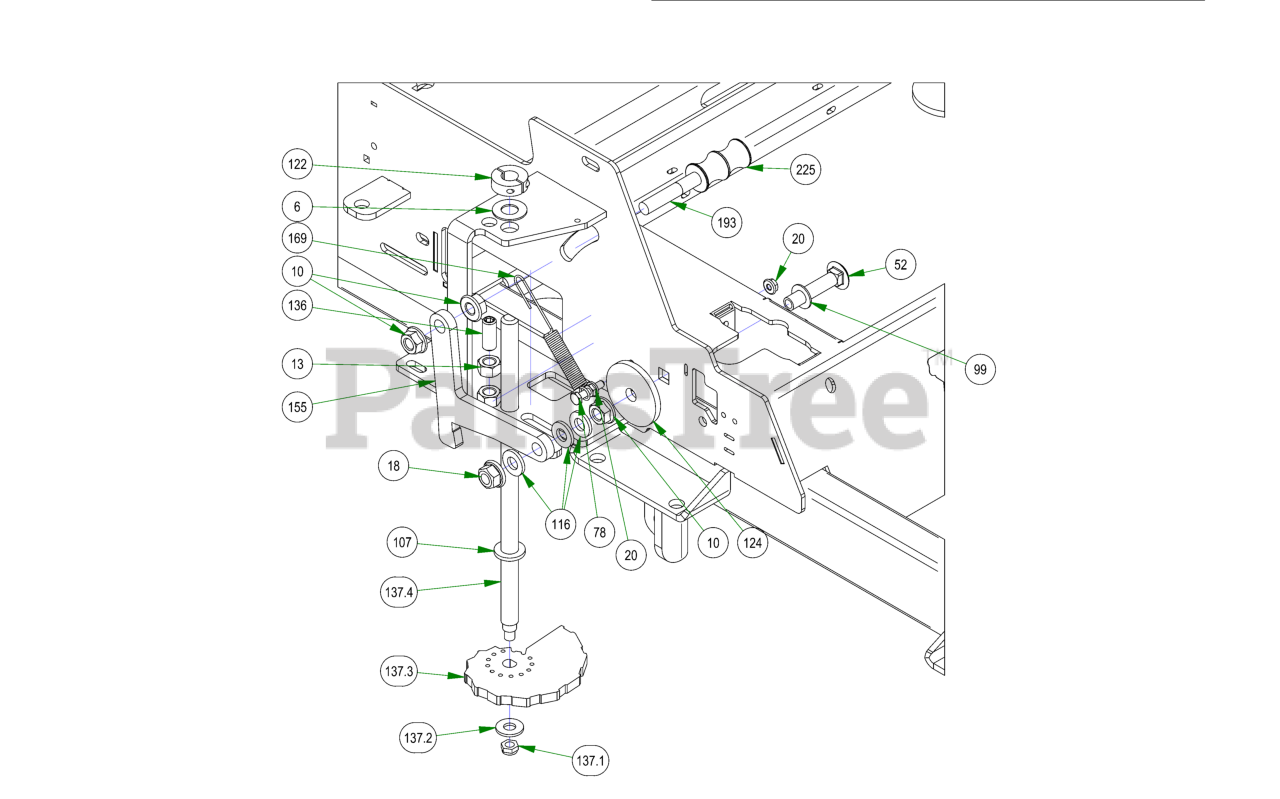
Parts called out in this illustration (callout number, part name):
6	.625 ID x 1.250 OD x .062 THK F/W Nylon
9	3/8-16 NYLON INSERT FLANGE LOCKNUT (GR.F) ZINC
10	1/2-13 HEX SERRATED FLANGE NUT HARD/ZINC
13	1/2-13 HEX NUT ZINC
18	1/2-13 NYLON INSERT FLANGE LOCKNUT ZINC
20	1/4-20 HEX SERRATED FLANGE NUT HARD/ZINC
21	5/16-18 HEX SERRATED FLANGE NUT HARD/ZINC
48	Pillow Block Assembly
48.1	Two Piece Pillow Block
48.2	Two Piece Pillow Block Strap
52	2 1/2 x 1/2 Carriage Bolt
73	13mm Damper Ball Stud-Steering
74	10mm Damper Ball Stud-XP Linkage
75	5/8 X 5/8 SOCKET SHOULDER BOLT ZINC YELLOW
76	1/2-13 NYLON INSERT JAM LOCKNUT ZINC
78	1/4-20 X 1-1/4 HEX CAP SCREW (GR.5) ZINC
81	1/2-13 X 4 HEX CAP SCREW (GR.8) ZINC YELLOW
83	3/8-16 X 1-1/4 CARRIAGE BOLT ZINC
99	.517 SQ WDTH ID X .937 OD X .060 THICK F/W PHOS/OIL
107	.635 ID X 1.120 OD X .140 THICK FLAT WASHER NYLON
116	.505 ID X 1.000 OD X .125 THICK FLAT WASHER NYLON
122	5/8" Split Collar
124	MZ Deck Idler Spacer
131	Knurled Pedal
136	Dial Rod Plunger
137	2019 Outlaw Gen2 Deck Height Dial Rod Assy
137.1	3/8-24 Nylon Insert jam locknut
137.2	3/8" Flat Washer
137.3	2019 Deck Height Cam
137.4	2019 Outlaw Gen2 Dial Rod
138	2019 Outlaw Actuator - Front
139	2019 Outlaw Actuator - Rear
141	2019 Actuator Linkage – Right – Black
142	2019 Actuator Linkage - Left - Black
152	Foot Lift Upright Lever
155	2019 Outlaw Deck Travel Lock
160	.627 ID X .753 OD X .500 LGTH X 1.000 FLG OD X .094 FLG
169	Brake Spring
179	Deck Hangar Assembly
179.1	1/2-13 HEX SERRATED FLANGE NUT HARD/ZINC
179.2	1/2-13 NYLON INSERT FLANGE LOCKNUT ZINC
179.3	1/2-13 X 2-1/4 HEX CAP SCREW (GR.5) ZINC
179.4	.505 ID X 1.000 OD X .125 THICK FLAT WASHER NYLON
179.5	Deck Hangar
193	Seat Bracket Pin
194	Security Ring - PC744
196	Foot Pedal Knob 1/2-13
225	Travel Lock Rubber Grip
230	2021 Rogue Suspension Frame Painted
253	200 lb Gas Spring- 54" Deck outlaw
254	250lb Gas Spring - 61" Deck
255	300lb Gas Spring - 72" Deck
274	2019 Rogue Cooler Cover Decal
